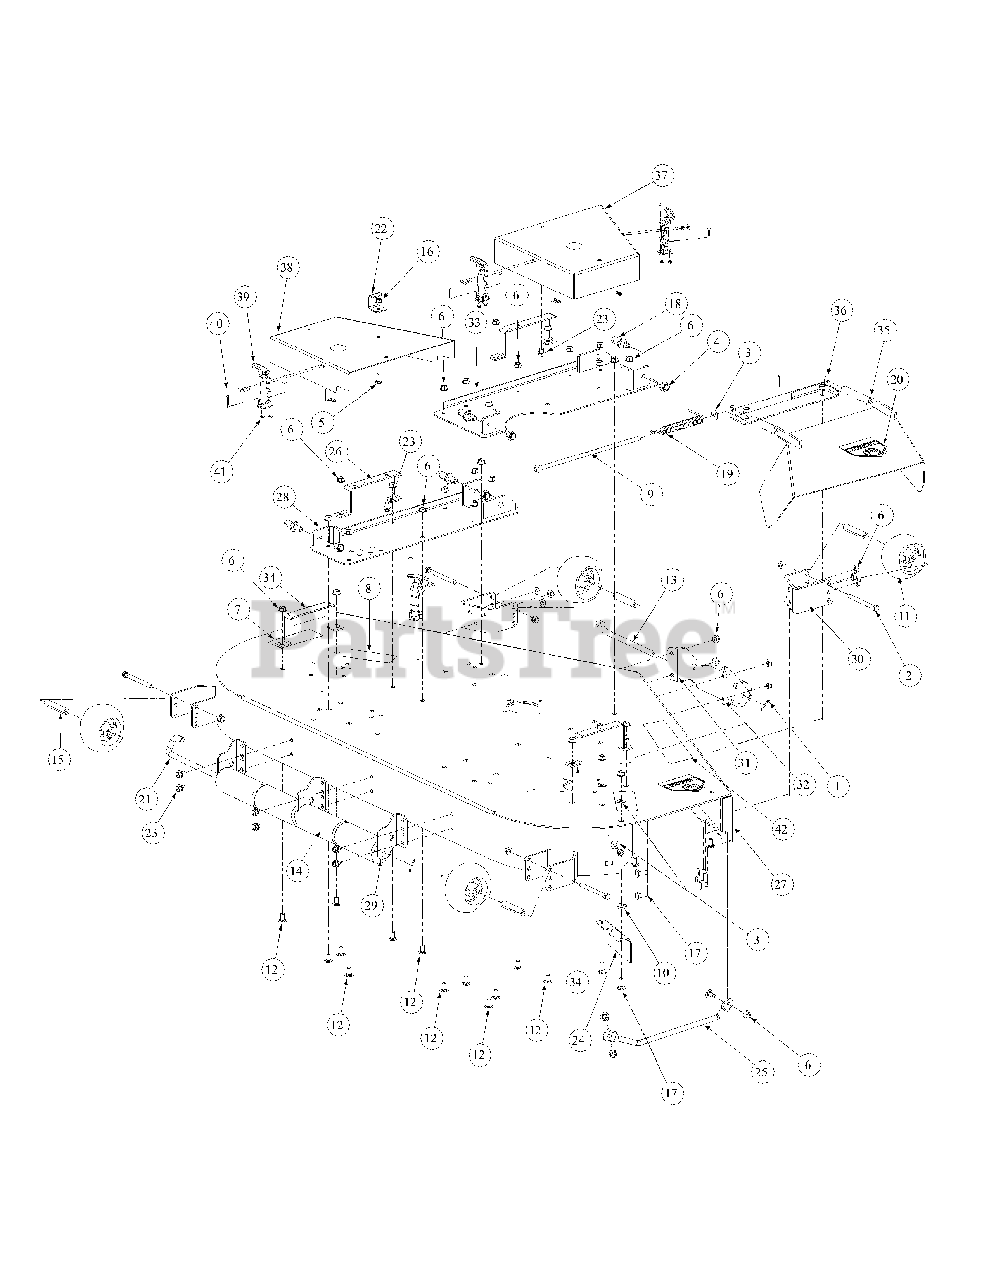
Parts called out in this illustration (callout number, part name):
1	Cotter Pin, .125 Dia. x 1.0
2	Hex Cap Screw, 3/8-16, 3.75
3	Flat Washer, 3/8
4	Lock Nut, Nylon Insert, 1/2-13
5	Hex Cap Screw, 5/16-18 x 3/4
6	Flange Lock Hex Nut, 3/8-16
7	Decal, Rotating Blade
8	Decal, Warning Shield Missing
9	Deflector Pivot Assembly, Pin
10	Idler Washer
11	Complete Wheel, 5.00 Dia.
12	Carriage Bolt, 3/8-16 x .75 Lg.
13	Roller Pin, 1/2 Dia. x 7.31 Lg.
14	Front Roller
15	Wheel Spacer
16	Hex Flange Lock Nut, 5/16-18
17	Carriage Bolt, 3/8-16 x 1
18	Pin, 5/8 Dia. x 1.2 Lg.
19	Torsion Spring
20	Decal, Danger Hand and Feet
21	Roller Pin
22	Tension Rod Stop Bracket
23	Hex Index Washer Screw, 3/8-16, .5
24	Chute Bracket
25	Finger Guard
26	Belt Cover Support
27	60 Deck Assembly
28	Left Hand Mount Deck Bracket Assembly
29	Deck Roller Mount Bracket
30	Anti-Scalp Wheel Front Mount Bracket
33	Right Hand Deck Bracket Assembly
34	Outer Belt Cover Support Assembly
35	Deck Weldment Chute Assembly
36	Chute Deck Bracket Weldment Mount
37	Right Hand Deck Belt Cover Weldment
38	Left Hand Deck Belt Cover Weldment
39	T-Handle Latch Draw
40	Phillips Head Screw, 10-32
41	Lock Nut, Nylon Insert, 10-32
42	Commercial Mower Label
